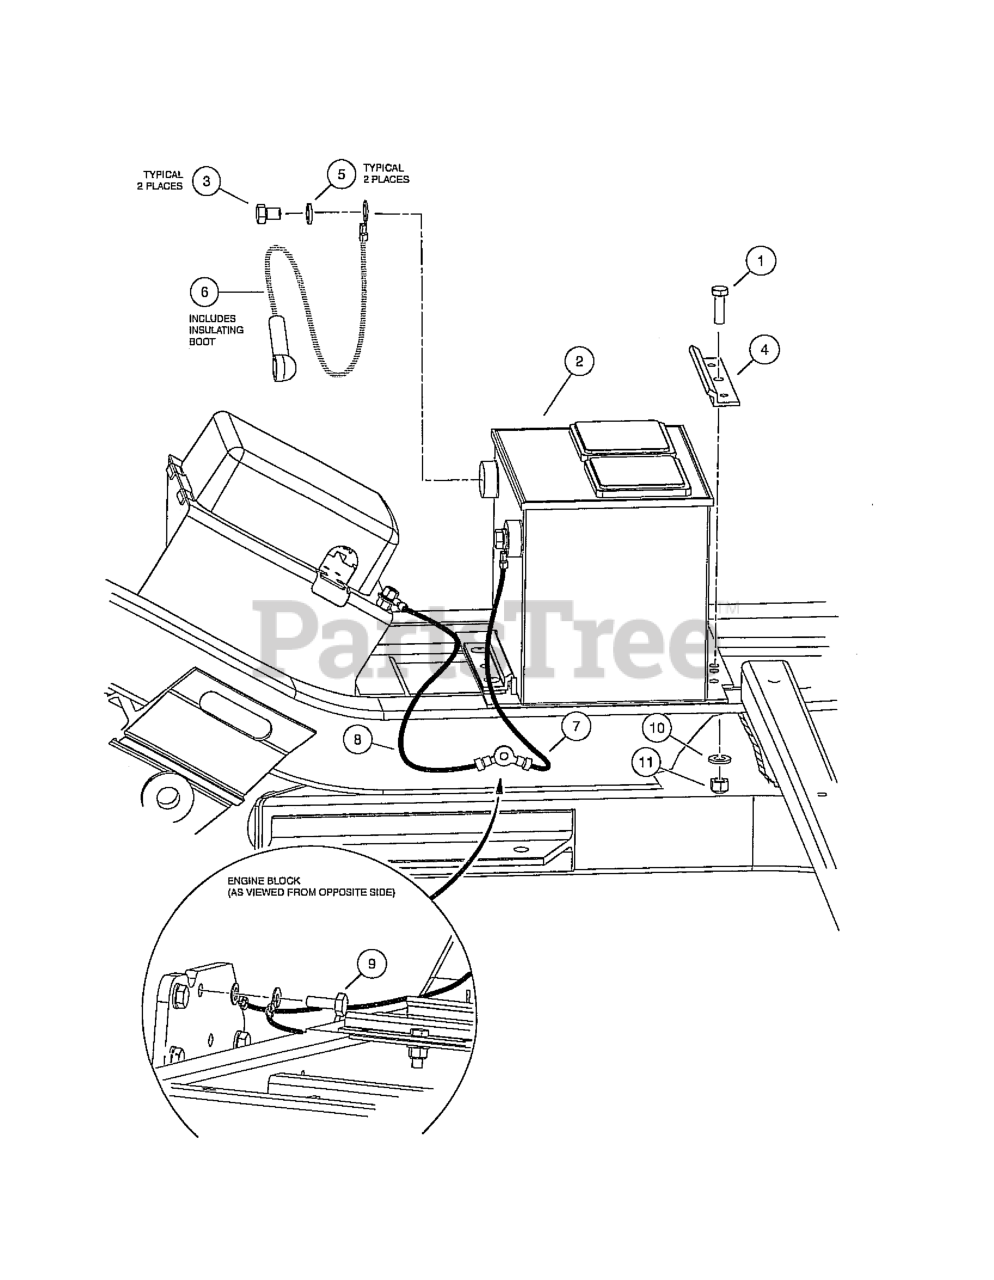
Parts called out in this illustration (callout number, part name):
1	SCREW HEX CAP
2	BATTERY, 12 VOLT
4	CLAMP - BATTERY
5	LOCKWASHER, 3/8 STAINLESS STL
6	WIRE ASM, #6 RED, AWD
7	WIRE ASM, #6 BLK, AWD, 350
8	WIRE ASM, #6 BLK, AWD, 325
9	BOLT, M10 X 1.25 X 25 LOCTITE
10	WASHER, 5/16 TYPE A FLAT
11	LOCKNUT, 5/16-18 NYLON INSERT
